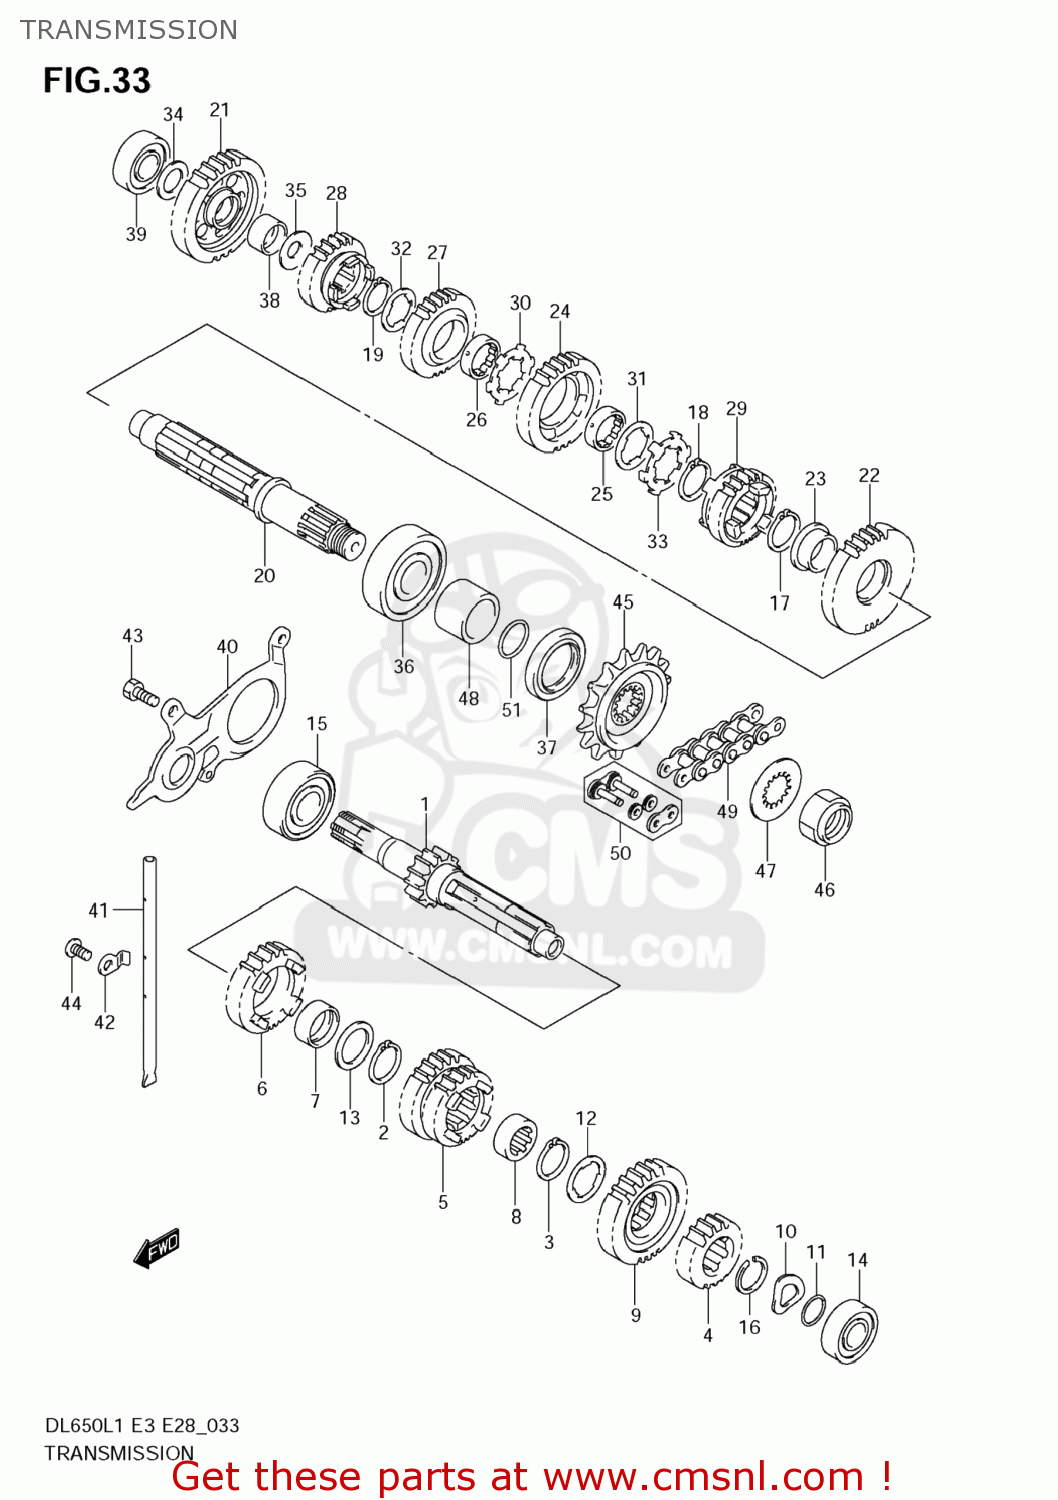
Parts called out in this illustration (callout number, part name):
1	SHAFT,COUNTER
2	CIRCLIP
3	CIRCLIP
4	GEAR,SECOND DRIVE (NT:18)
5	GEAR,3RD & 4TH DRIVE
6	GEAR,5TH DRIVE(NT:26)
7	BUSH
8	BUSH,6TH DRIVE GEAR
9	GEAR,6TH DRIVE(NT:27)
10	WASHER
11	O RING(D:1,ID:16.8)
12	WASHER,LOCK
13	SHIM(25X34X1)
14	BEARING(17X40X12)
15	BEARING(20X52X15)
16	CIRCLIP
17	CIRCLIP
18	CIRCLIP
19	CIRCLIP
20	SHAFT,DRIVE
21	GEAR,1ST DRIVEN(NT:32)
22	GEAR,2ND DRIVEN.NT:32)
23	BUSH
24	GEAR,3RD DRIVEN(NT:29)
25	BUSH,DRIVEN GEAR
26	BUSH,DRIVEN GEAR
27	GEAR,4TH DRIVEN(NT:27)
28	GEAR,5TH DRIVEN(NT:25)
29	GEAR,6TH DRIVEN(NT:23)
30	WASHER,LOCK
31	WASHER,LOCK
32	WASHER,LOCK
33	WASHER
34	SHIM(17X28X1)
35	SHIM(20X30X1)
36	BEARING(25X62X17)
37	SEAL,OIL(36X50X6)
38	BUSH(20X24X13)
39	BEARING(17X40X12)
40	RETAINER,DRIVE SHAFT OIL SEAL
41	GUIDE,T/M OIL
42	RETAINER,TRANSMISSION OIL
43	BOLT
44	SCREW
45	SPROCKET,ENGINE(NT:15)
46	NUT
47	WASHER,LOCK
48	SPACER,ENGINE SPROCKET
49	CHAIN,DRIVE
50	JOINT SET,CHAIN
51	O RING(D:2.4,ID:23.7)
